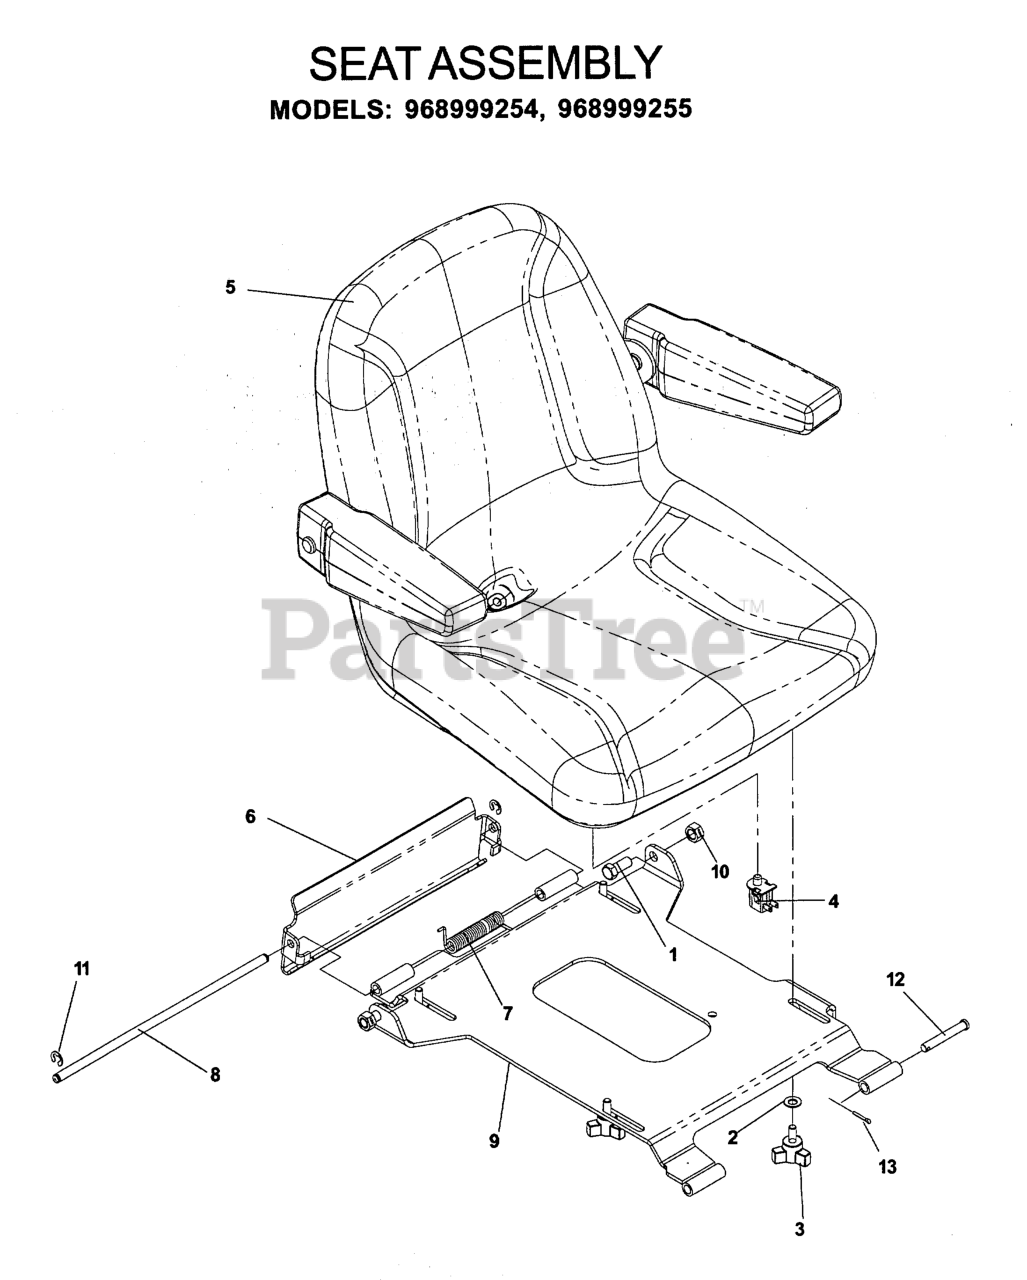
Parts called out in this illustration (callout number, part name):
1	HCS 7/16-14 X 1 GR 5 ZD
2	WASHER, 3/8 DISC SPRING SPEC
3	KNOB W/STUD
4	SEAT SWITCH
5	SEAT W/ARMRESTS
6	SEAT LATCH BRACKET
7	TORSION SPRING (SEAT)
8	SEAT LATCH ROD
9	SEAT MOUNT WLDMT, PAN
10	NUT 7/16C CENTERLOCK
11	E RING 3/8"
12	CLEVIS PIN 3/8
13	RP_COTTER PIN 1/8 X 3/4
